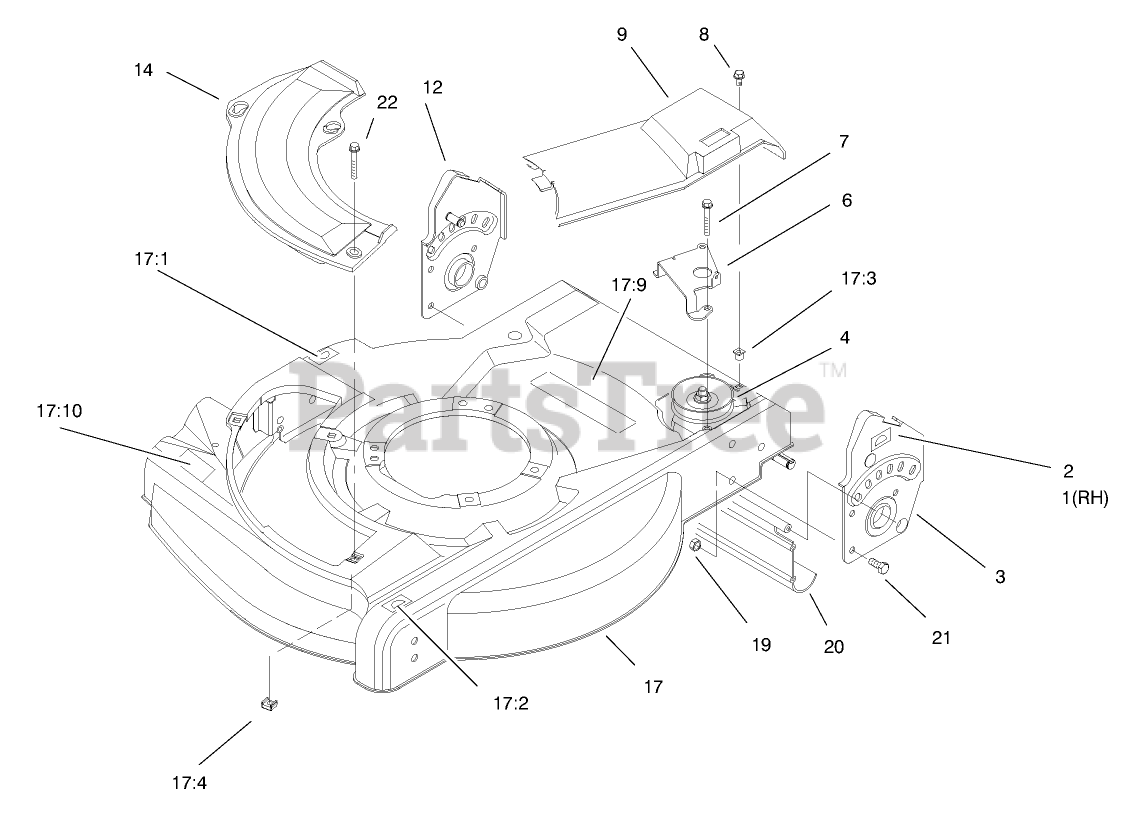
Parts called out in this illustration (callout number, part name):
7	SCREW-HWHTF
8	SCREW-TAP
9	COVER-DRIVE
14	PLATE-OPENING, CHUTE
17	HOUSING
17:1	DECAL-HOC, RH
17:2	DECAL-HOC, LH
17:3	NUT-CLIP
17:4	NUT-CAGE
17:9	DECAL-DANGER
17:10	DECAL-WARNING
19	NUT-LOCK, NI
20	SHIELD-TRAILING
21	SCREW-HH
22	SCREW-HWH
